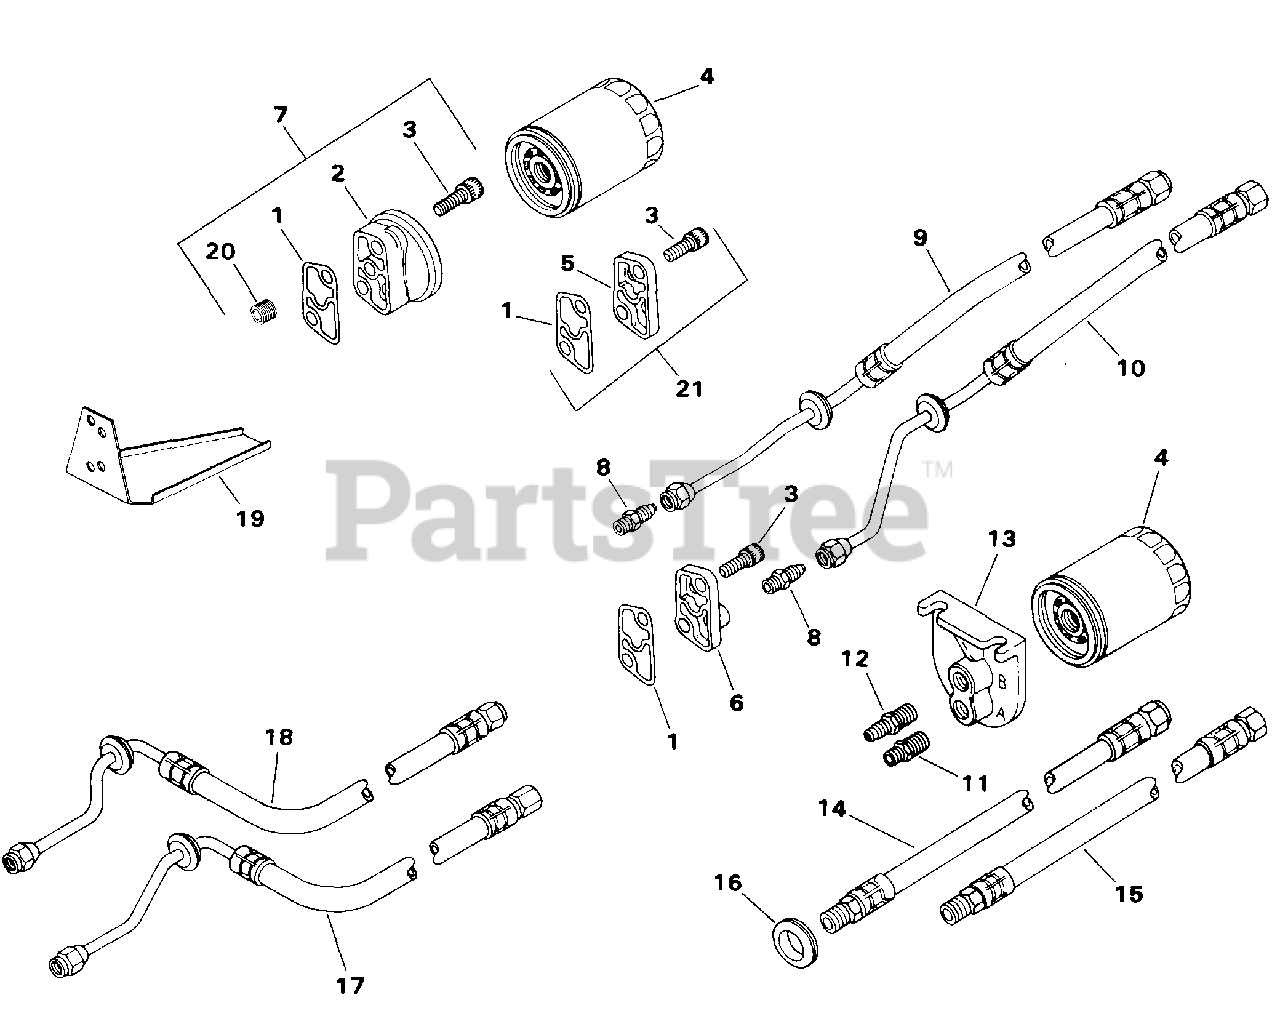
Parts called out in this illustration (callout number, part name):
2	KIT - USE 82 755 23
3	SCREW, HEX SOCKET HEAD CAP USE 25 086 89-S
4	FILTER, OIL
